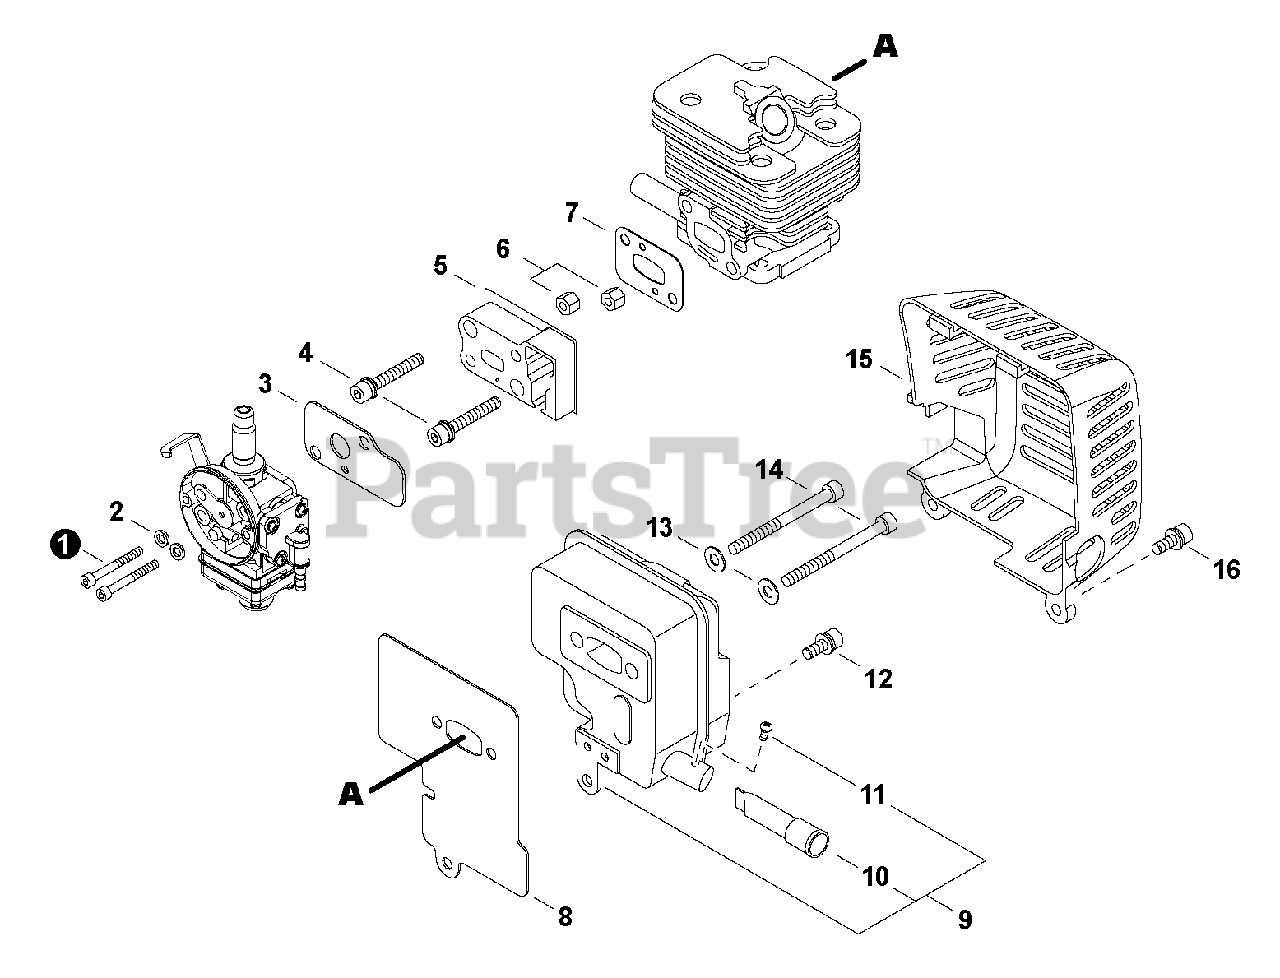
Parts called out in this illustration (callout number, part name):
1	Bolt M5x65
2	Washer, Spring 5
3	Gasket, Carburetor
5	Insulator
7	Gasket, Intake
8	Gasket, Muffler
9	Muffler Assy
10	Screen, Spark Arrester
11	Screw, Tapping 3x6
12	Bolt 5
13	Washer, Flat 5.5x10x0.8
14	Bolt 5x55
15	Cover, Muffler
16	Bolt M5x16
